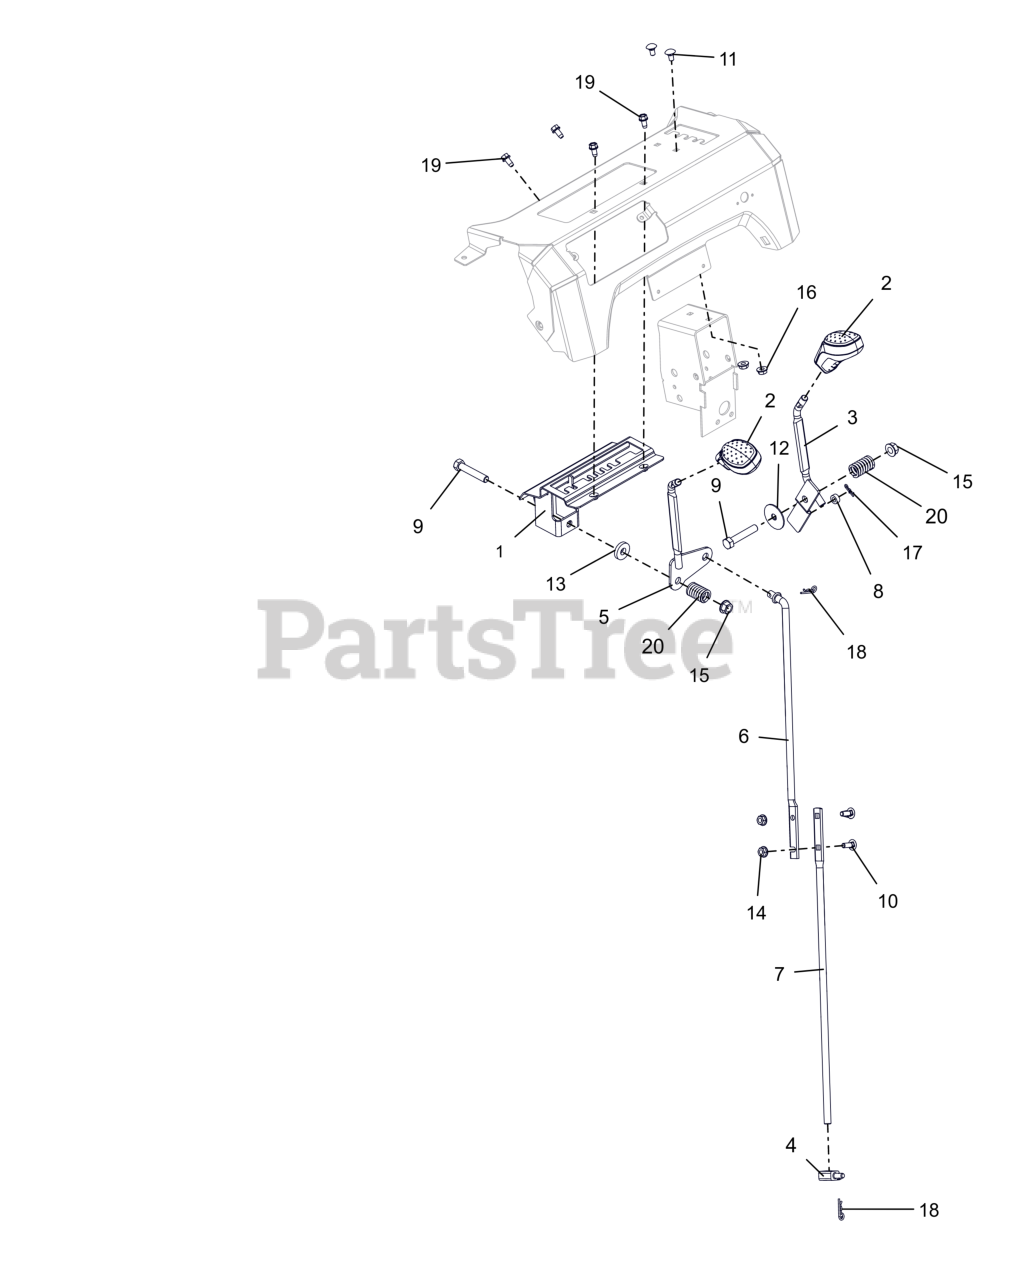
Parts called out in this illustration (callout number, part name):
1	WELDMENT, DETENT PLATE-COMPACT
2	KNOB, CONTROL, DASH
3	WELDMENT,SM DASH DEFL CONTROL
4	PIVOT,SHIFT ROD .375-16(TRUNN)
5	LEVER, CONTROL-SHIFT(WELDMENT)
6	ROD, SHIFT - UPPER
7	ROD, SHIFT-LOWER (SM DASH DLX)
8	BSHG-SLV .265X.500X.219
9	BLT,HEX .38-16X2.00 G5 ZCC
10	BLT, RHSN .25-20X.750 G5 ZCC
11	BLT, RHSN .25-20X.500 G5 ZCC
12	WSHR,FLT .380X1.50X.062 ZCC
13	WSHR, FLT .406X1.00X.188 ZCC
14	NUT-LK-CTR-FLG .25-20 ZC120
15	NUT-LK-TOP-FLG .38-16 ZC120
16	NUT-LK-TOP-FLG .250-20 GF ZCC
17	PIN, HAIR #178 .06X.77 ZCC
18	PIN, HAIR #213 .08X1.19 ZCC
19	SCR-TAP .25-20X.50 HWH ZCC
20	SG-COMP .125X.781X1.250
